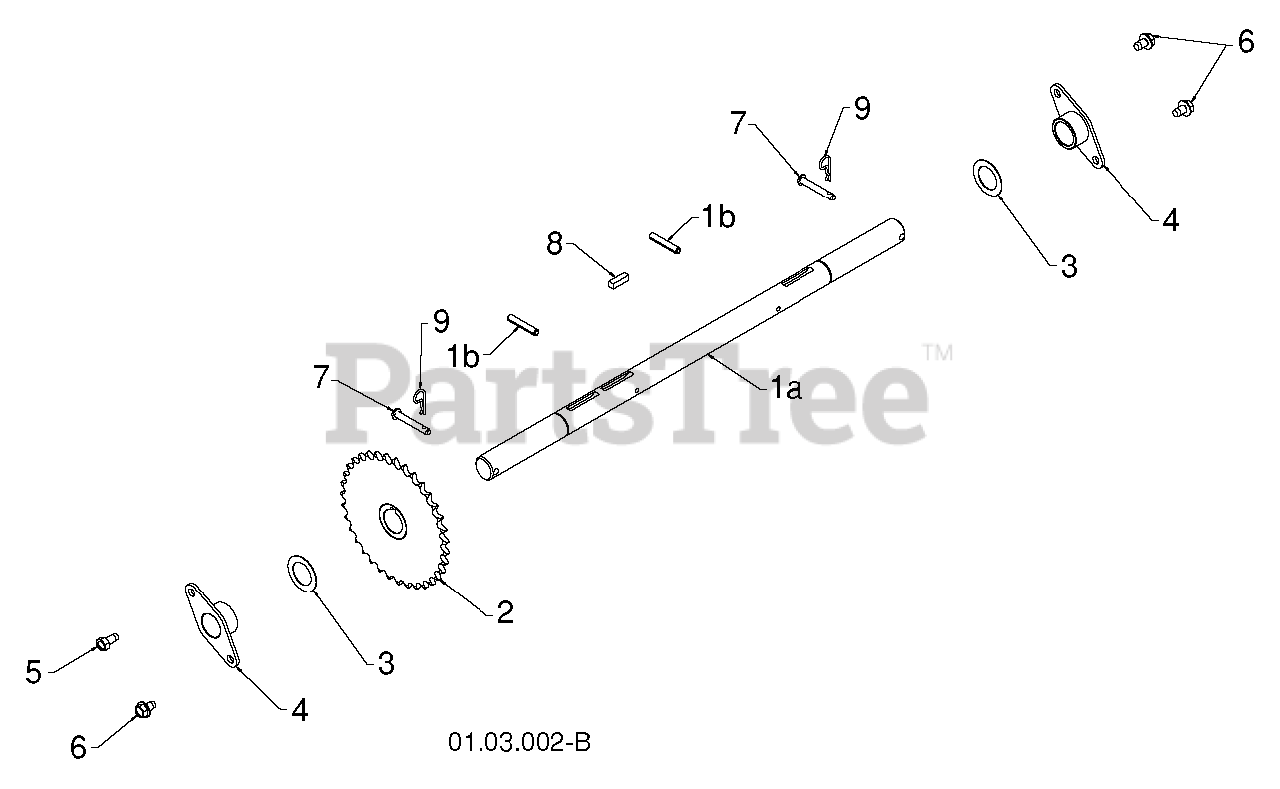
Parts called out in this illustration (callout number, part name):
1	AXLE.ASM.SHAFT.W/ROLLPIN.PS
2	SPROCKET.WELDMENT.AXLE.1.00
3	WASHER 1.00
4	BEARING, AXLE
6	SCREW LT
8	KEY, SQUARE 1/4 X .875
